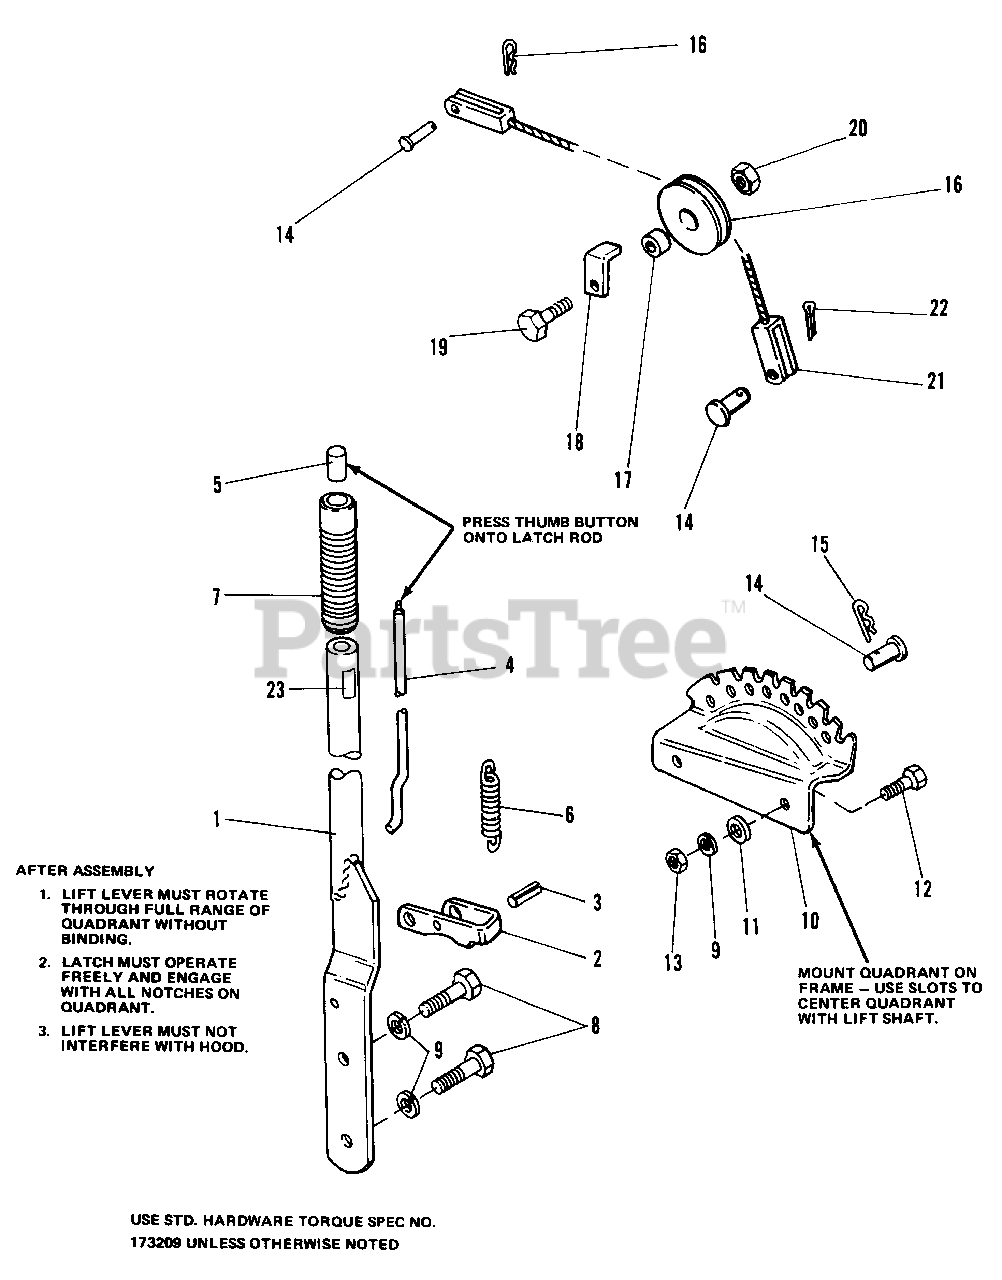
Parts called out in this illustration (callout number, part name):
1	LIFT LEVER ASSEMBLY
2	LATCH, Lift Lever
3	PIN, Spring, 3/8 x 1-1/4
4	ROD, Latch
7	GRIP
8	CAPSCREW, Hex Hd., 3/8-16 x 1
9	LOCKWASHER. 3/8
11	WASHER, 5/16
12	CAPSCREW, Hex Hd., 3/8-16 x 3/4
13	NUT, Hex, Full, 3/8-16
15	CLIP, Spring
18	GUARD, Cable
20	LOCKNUTS, Hex,Jam, 3/8-16
21	LIFT CABLE ASSY
22	PIN, Cotter, 3/32 x 7/8
23	FILM, Lift Lever
